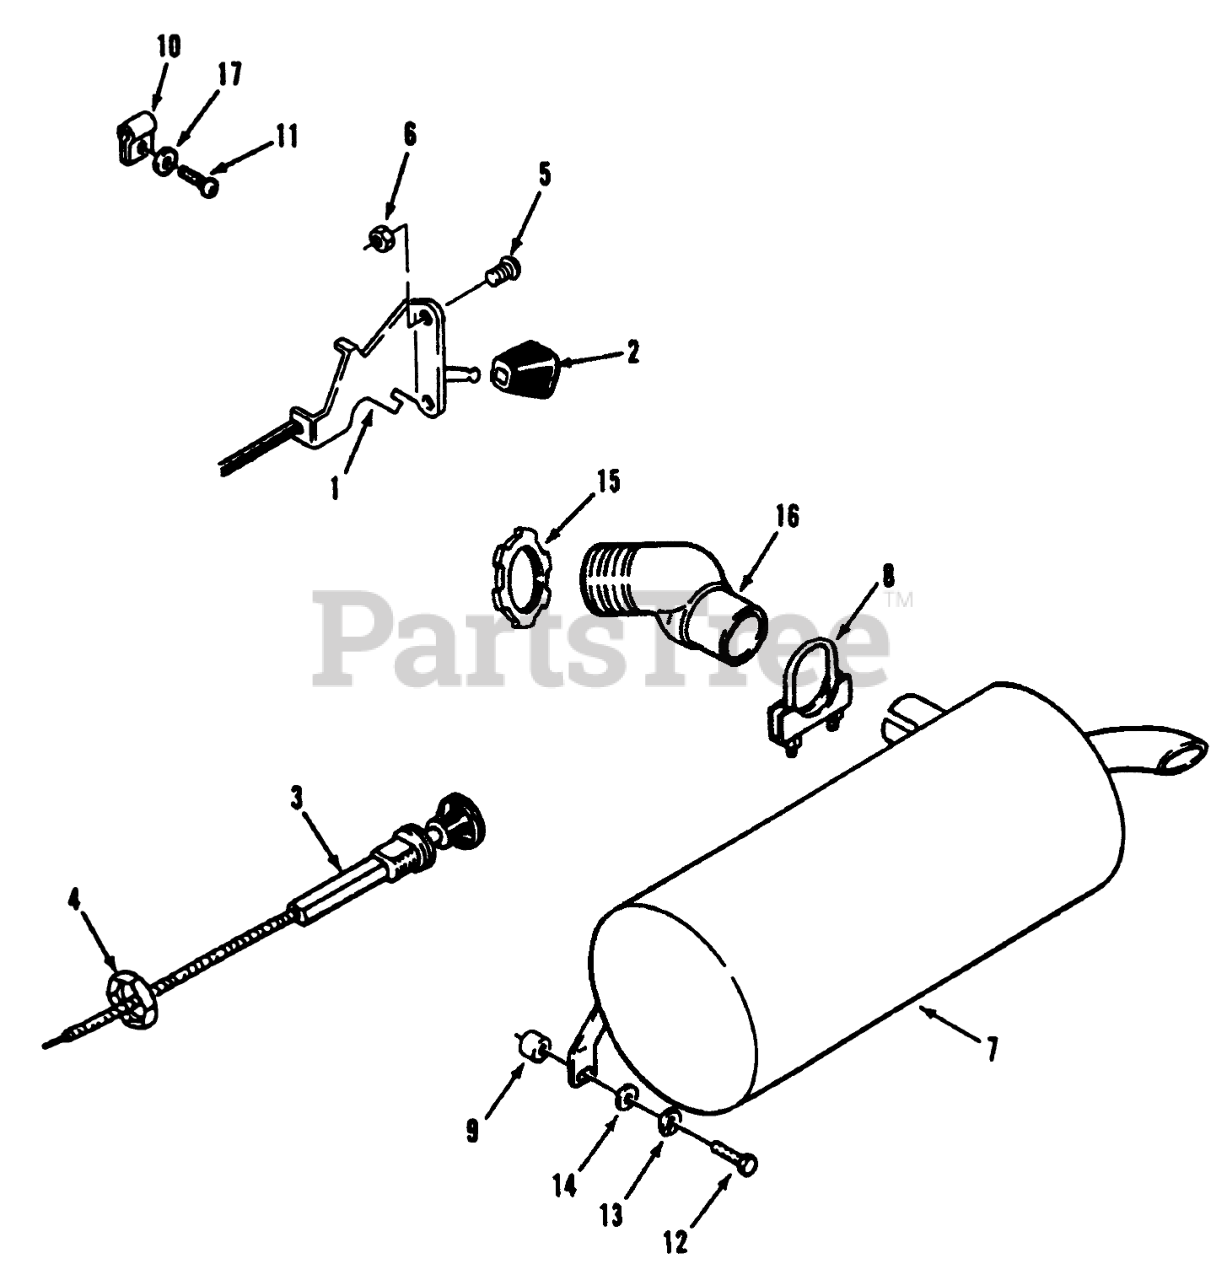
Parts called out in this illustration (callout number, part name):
1	Control-Throttle
2	KNOB-CONTROL
3	CONTROL CHOKE
4	NUT-HEX PALNUT
5	Screw
6	Nut
7	Muffler
8	CLAMP-1 1/2
9	SPACER
11	Screw
12	SCREW-HH
13	WASHER-LOCK
14	WASHER-FLAT
15	Nut-Lock
16	Elbow
17	Washer
